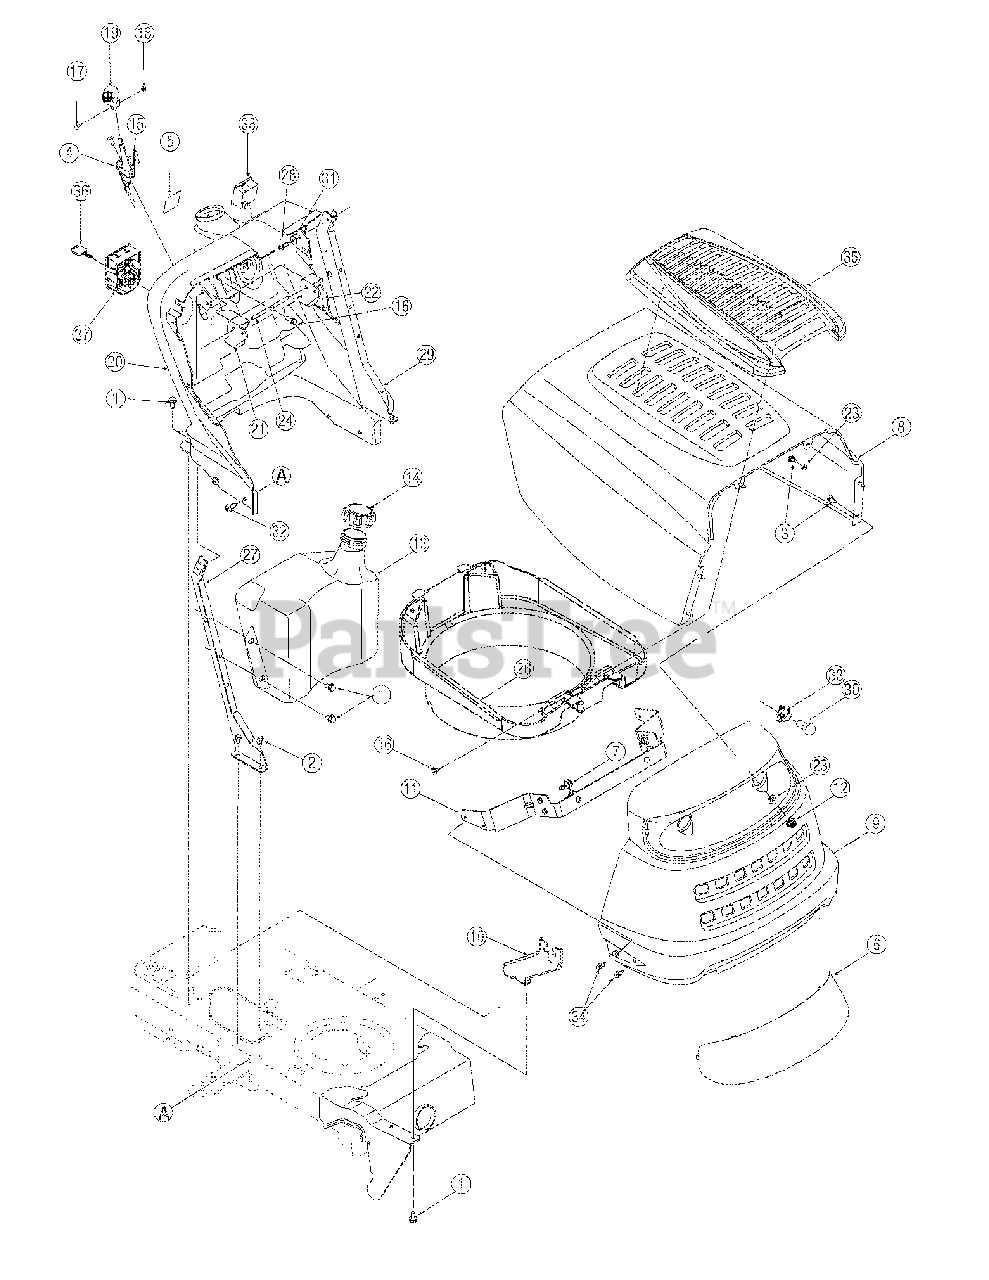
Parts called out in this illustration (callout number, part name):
1	Screw, 5/16-12 x.750
2	Self-tapping Screw, 1/4-20 x.5
3	Hex Cap Screw, 1/4-20 x.62
4	Throttle Control/Cable
5	Choke Plug
6	Headlight Lens
7	Shoulder Screw,.43 x.29
10	Pivot Bracket - LH
11	Grill Pivot Bracket
12	Flange Lock Nut, 1/4-20
13	Fuel Tank, Two Gallon
14	Fuel Cap
15	Screw, 1/4-14 x.625
16	Self-tapping Screw, 1/4-15 x.75
17	Truss Phillips Screw, #8-32 x.375
18	Hex Nut, #8-32
19	Throttle Control Knob
20	Dash Panel
21	Cruise Control Button
22	Parking Brake Button
23	Flat Washer, .265 x .938 x 1.20
24	Brake/Cruise Pivot Rod
26	Hood Plenum
27	RH Dash Support Plate
28	Self-tapping Screw, 1/4-20 x .75
29	LH Dash Support Plate
31	Bell Washer,.265 x.75 x.062
32	Screw, 5/16-18 x.75
33	Headlight Socket
34	Hex Index Screw, 1/4-20 x .625
35	Hood Cover, 5 Style
36	Ignition Key w/ plastic cover
36	Ignition Key w/o plastic cover
37	Ignition Switch
38	Systems Ind. Monitor w/ Hour Meter (if equipped)
38	Systems Ind. Monitor w/Ammeter
